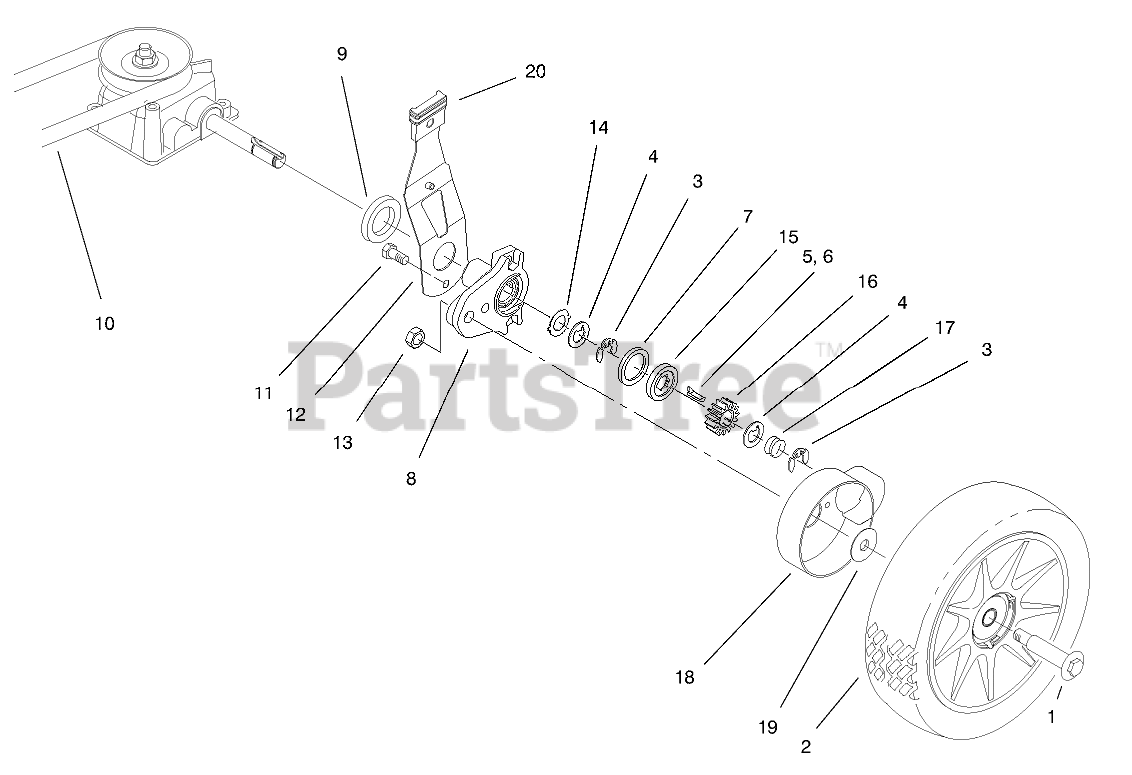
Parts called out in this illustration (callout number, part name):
1	BOLT-SHOULDER
2	WHEEL AND TIRE ASM
3	RING-CLIP, LOCKING
4	WASHER-THRUST, KEYED
5	KEY-ROCKING, LH
6	KEY-ROCKING, RH
7	RING-FRICTION
8	REAR HEIGHT ADJUSTMENT ARM ASM
9	SPACER-AXLE SHAFT
10	V-BELT
11	SCREW-HWH
12	REAR SPRING ARM ASM
13	NUT-JAM, LOCKING
14	WASHER-ARM, PIVOT
15	WASHER-CLUTCH
16	GEAR-PINION
17	SPRING-COMPRESSION
18	COVER-WHEEL
19	WASHER-STEPPED
20	KNOB-LEVER, HEIGHT ADJUSTMENT
